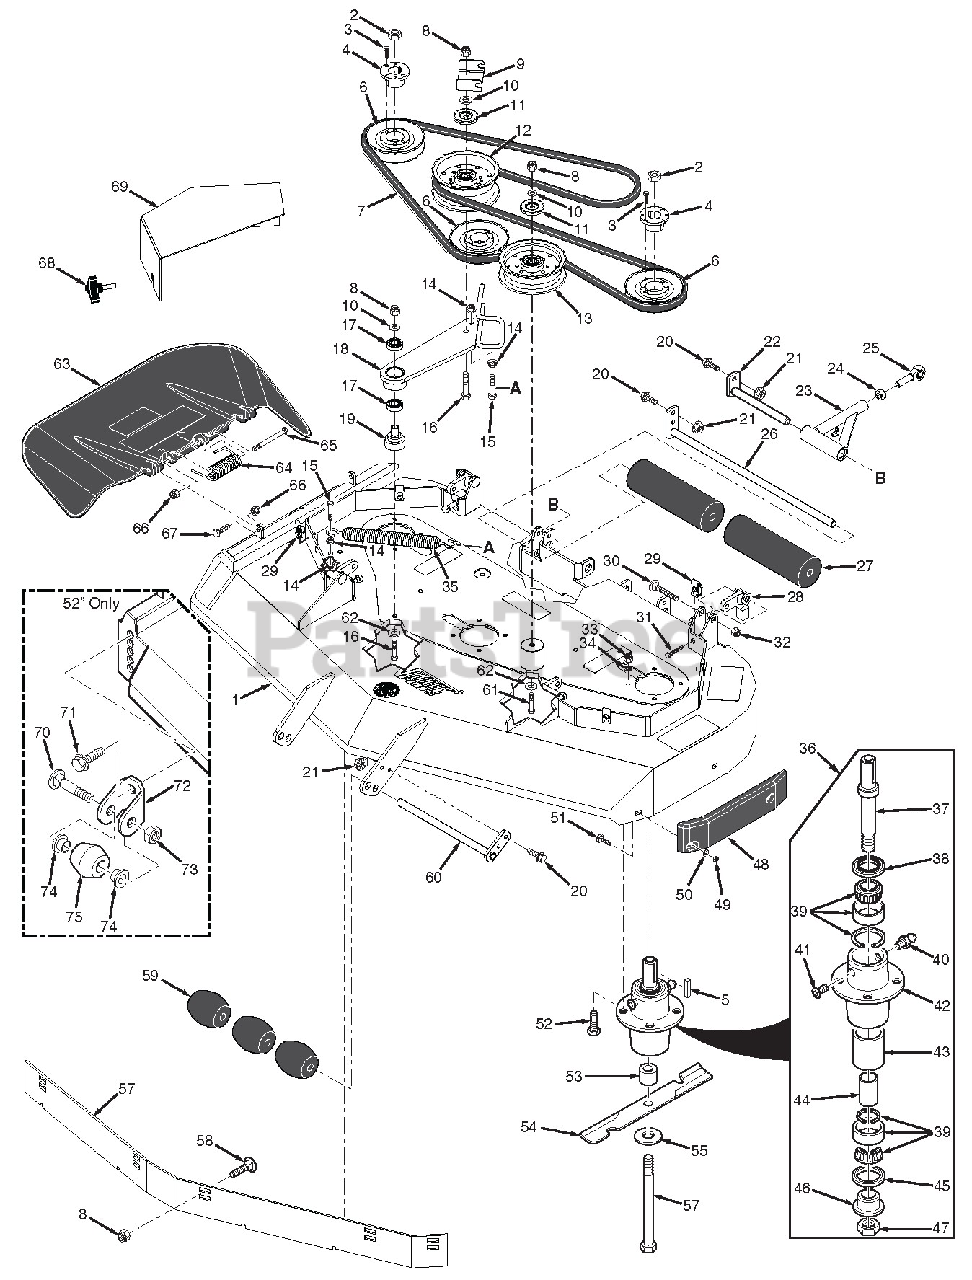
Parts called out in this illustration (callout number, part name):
1	Cutter Deck w/Decals (48V)
1	Cutter Deck w/Decals (52V)
2	Nut, 5/8-11 UNC
3	Bolt, Hex Head 1/4-20 x 1"
4	Tapered Hub
5	Key, 1/4 x 1/4 x 1"
6	Pulley, 5.13 OD (48V)
6	Pulley, 5.73 OD (52V)
7	Belt, Cutter Deck (48V)
7	Belt, Cutter Deck (52V)
8	Nut, Elastic Stop 3/8-16
9	Bracket, Belt Guide
10	Flatwasher, 3/8-.391 x .938 x .105 HD
11	Dust Shield
12	Pulley, 5" Idler
13	Pulley, 5" Idler
14	Nut, Serrated Flange 3/8-16
15	Bolt, Hex Head 3/8-16 x 1-1/2" Gr.8
16	Bolt, Hex Head 3/8-16 x 3-1/4"
17	Bearing
18	Idler Arm Assembly - 48V
18	Idler Arm Assembly - 52V
19	Pivot, Idler
20	Bolt, Hex Head 5/16-18 x 1"
21	Nut, Serrated Flange 5/16-18
22	Shaft Weldment, Pusharm Mount
23	Pusharm Assembly, LH
23	Pusharm Assembly, RH
24	Nut, 1/2-20 UNF
25	Rod End, 1/2-20 RH
26	Shaft Weldment
27	Guide Roller
28	Lever, Deck Level
29	U-Nut, 3/8-16
30	Bolt, Carriage 7/16-14
31	Bolt, Hex Head 3/8-16 x 2" Special
32	Nut, Elastic Stop 7/16-14
33	Nut, Elastic Stop 5/16-18
34	Lockwasher, 5/16" Spring
35	Spring, Cutter Deck
36	Spindle Assembly
37	Shaft, Spindle
38	Seal, Upper
39	Bearing Assembly
40	Grease Fitting
41	Valve Grease Relief
42	Housing, Spindle
43	Spacer, Outside
44	Spacer, Inside
45	Seal, Lower
46	Bushing, Lower
47	Nut, Special 1-1/16" - 18
48	Pad, Deck Wear
49	Nut, Center Lock 5/16-18
50	Flatwasher, 5/16-.344 x .688 x .065
51	Bolt, Carriage 5/16-18 x 3/4"
52	Bolt, Hex Head 5/16-18 x 1-3/4"
53	Spacer, Spindle Bottom
54	Cutter Blade, 16-1/2" (48V)
54	Cutter Blade, 18" (52V)
55	Flatwasher, 5/8-.688 x 1.75 x .134 HD
56	Bolt, Hex Head 5/8-11 x 9-1/2"
57	Baffle, Flange 48V
57	Baffle, Flange 52V
58	Bolt, Carriage 3/8-16 x 1"
59	Wheel Anti-Scalp
60	Shaft Weldment
61	Bolt, Carriage 3/8-16 x 5"
62	Flatwasher, 3/8-.406 x 2.25 x .1875
63	Discharge Chute Assembly - 48V
63	Discharge Chute Assembly - 52V
64	Spring, Discharge Chute
65	Bolt, Hex Head 5/16-18 x 4-3/4"
66	Nut, Elastic Stop 5/16-18
67	Bolt, Hex Head 5/16-18 x 1-3/4"
68	Knob w/Stud
69	Belt Cover, RH (48V)
69	Belt Cover, RH (52V)
69	Belt Cover, LH (48V)
69	Belt Cover, LH (52V)
70	Bolt, Carriage 3/8-16 x 4"
71	Bolt, Hex Serr. Flange 3/8-16 x 1"
72	Anti-Scalp Wheel Bracket
73	Nut, 3/8-16 Center Lock
74	Bushing, .376 I.D. Oilite
75	Anti-Scalp Wheel
